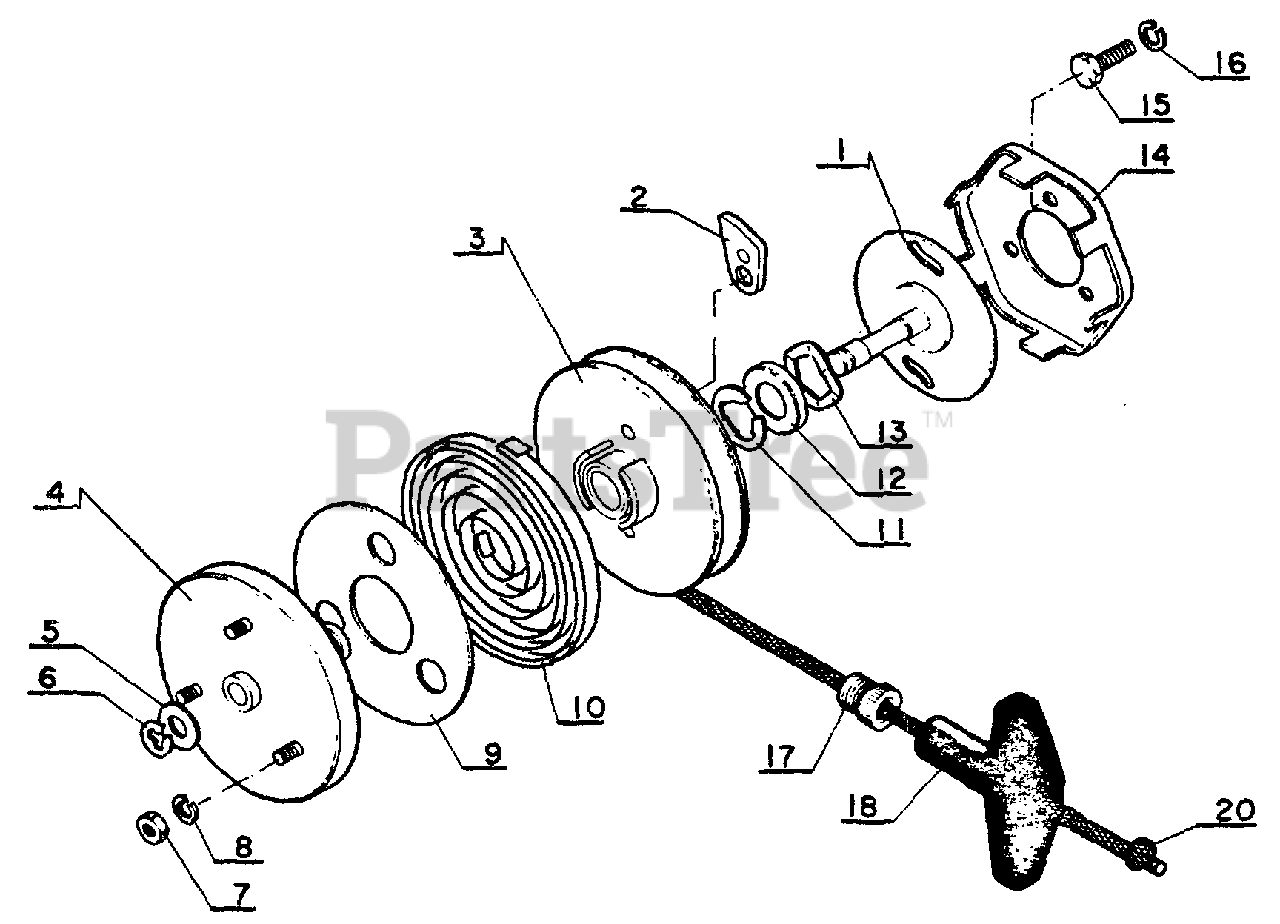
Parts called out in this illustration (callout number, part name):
1	PLATE, GUIDE
3	REEL, ROPE
4	RETAINER, SPRING
6	RING, RETAINING - 6
8	WASHER, SPRING 5
9	PLATE, SIDE
10	SPRING, RECOIL
11	RING, RETAINING
14	PAWL CATCHER
15	BOLT - 6×14
16	WASHER, SPRING 6
17	GUIDE, ROPE
